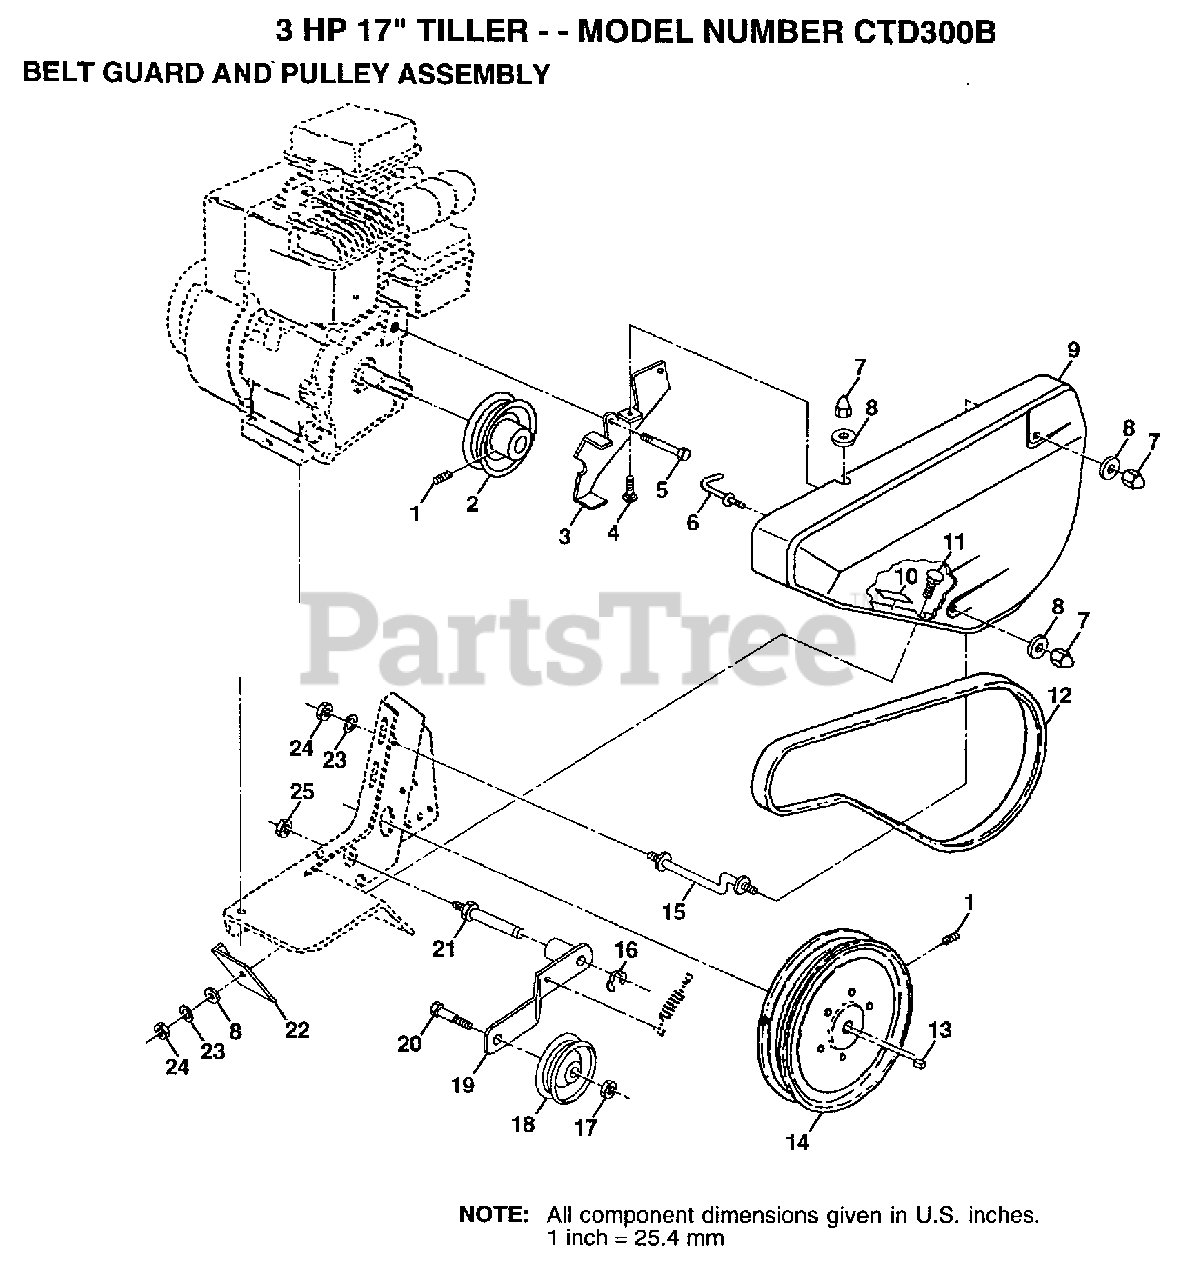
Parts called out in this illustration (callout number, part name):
1	SET SCREW
4	BOLT
7	NUT-CAP TI
8	WASHER
10	PAD IDLER TI
11	BOLT T
13	KEY T
14	TRANS SHEAVE RT
16	KLIP RING TI
17	NUT
19	IDLER ARM TI
21	SHAFT IDLER TI
22	SHIELD-DIRT TI
23	LOCKWASHER
25	JAM NUT TI
